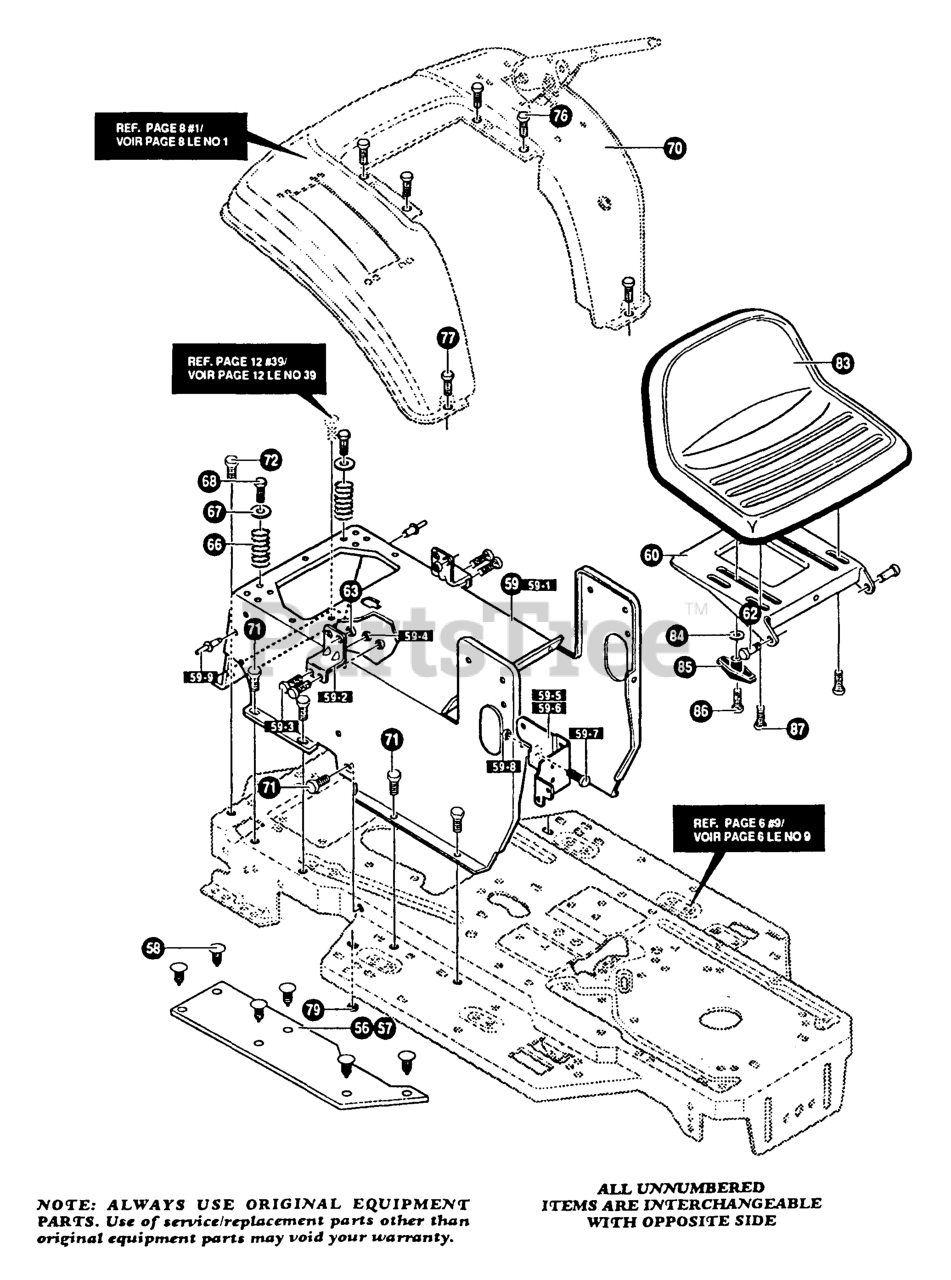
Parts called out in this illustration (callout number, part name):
56	FOOT PAD, LH
57	FOOT PAD, RH
58	FASTENER
59	ASSY, CONSOLE
59-2	BRACKET, SEAT SUPPORT
59-3	SCREW
59-5	BRKT, DASH/TANK, RH
59-6	BRKT, DASH/TANK, LH
59-9	RIVET
60	PLATE, SEAT
66	SPRING, SEAT
67	WASHER
70	FENDER
72	SCREW
84	WASHER
85	HANDLE
